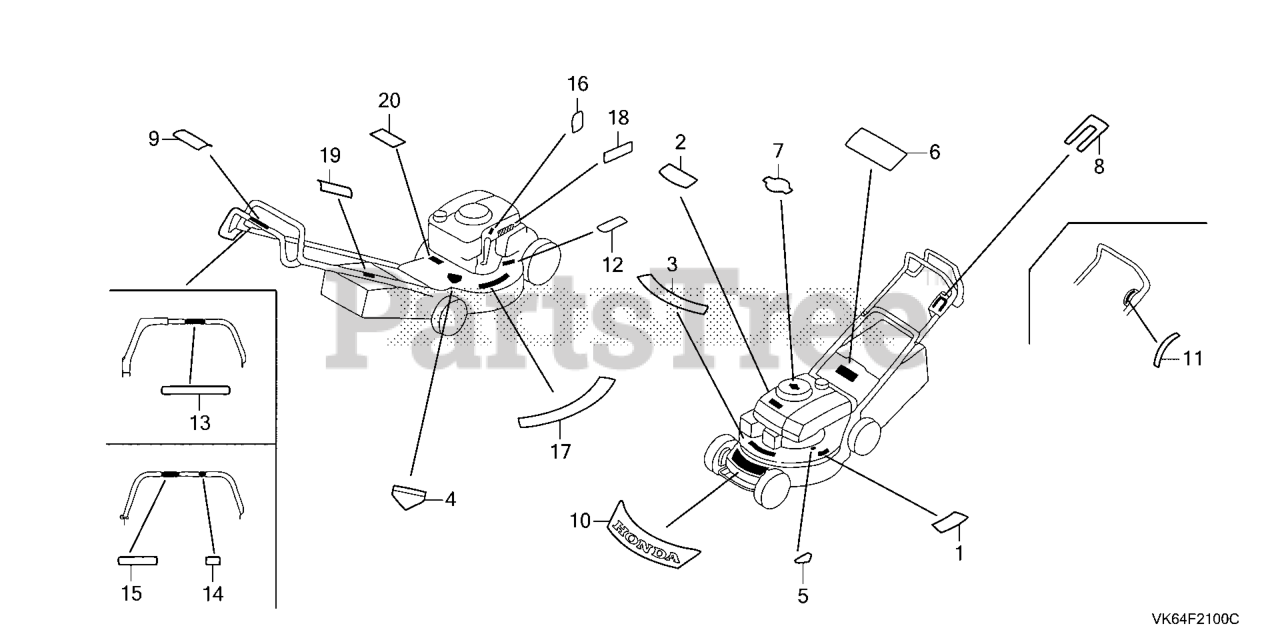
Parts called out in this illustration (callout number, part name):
2	MARK, EMBLEM
4	LABEL C, HOUSING CAUTION
6	LABEL, WARNING (ENGLISH)
7	MARK, RECOIL COVER
10	MARK, HONDA
11	MARK, THROTTLE (ENGLISH)
12	LABEL, HEAT WARNING
14	MARK, BLADE CONTROL
15	MARK, BLADE CONTROL (ENGLISH)
16	MARK, OIL CAUTION
17	MARK, SALES POINT
18	MARK, OIL RECOMMENDED
